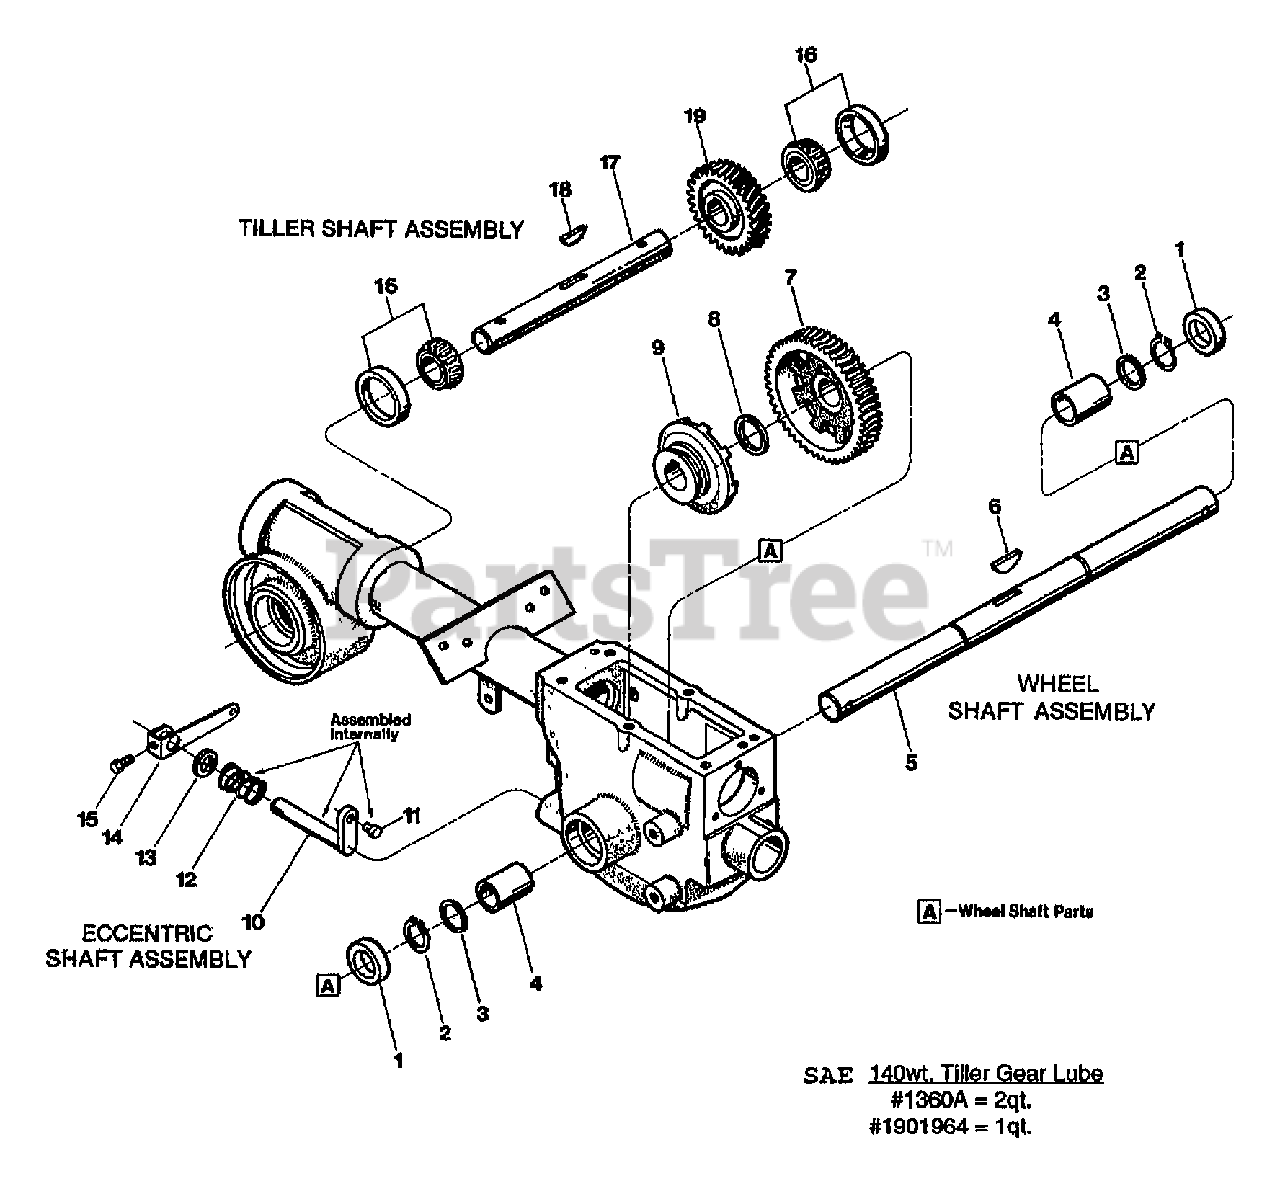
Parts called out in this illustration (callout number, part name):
1	SEAL-OIL WHEELSHAFT
2	RING-HEAVY EXT .906 ID
3	SHIM-1.375X1.015X.062
4	BUSHING-1.25X1.005X1.5
5	WHEELSHAFT W/KEY
6	KEY-HI PRO .25X1.312
7	GEAR-WORM 46 TEETH MACH
8	WASHER-1.468X1.016X.062
9	CLUTCH-MACH
10	WELD-ECCENTRIC
11	PIN-.375 X .72
12	SPRING-.850 X .875 LONG
13	SEAL-OIL ECCENTRIC
14	LEVER-CABLE ADJ PNT
15	SCR-HH 1/4-20X.5 GR5 YEL
16	BEARING CUP & CONE (W/RACE)
17	SHAFT W/KEY (TILLER)
18	KEY-WOODRUFF .25X1.12
19	GEAR-TILLER MACH
